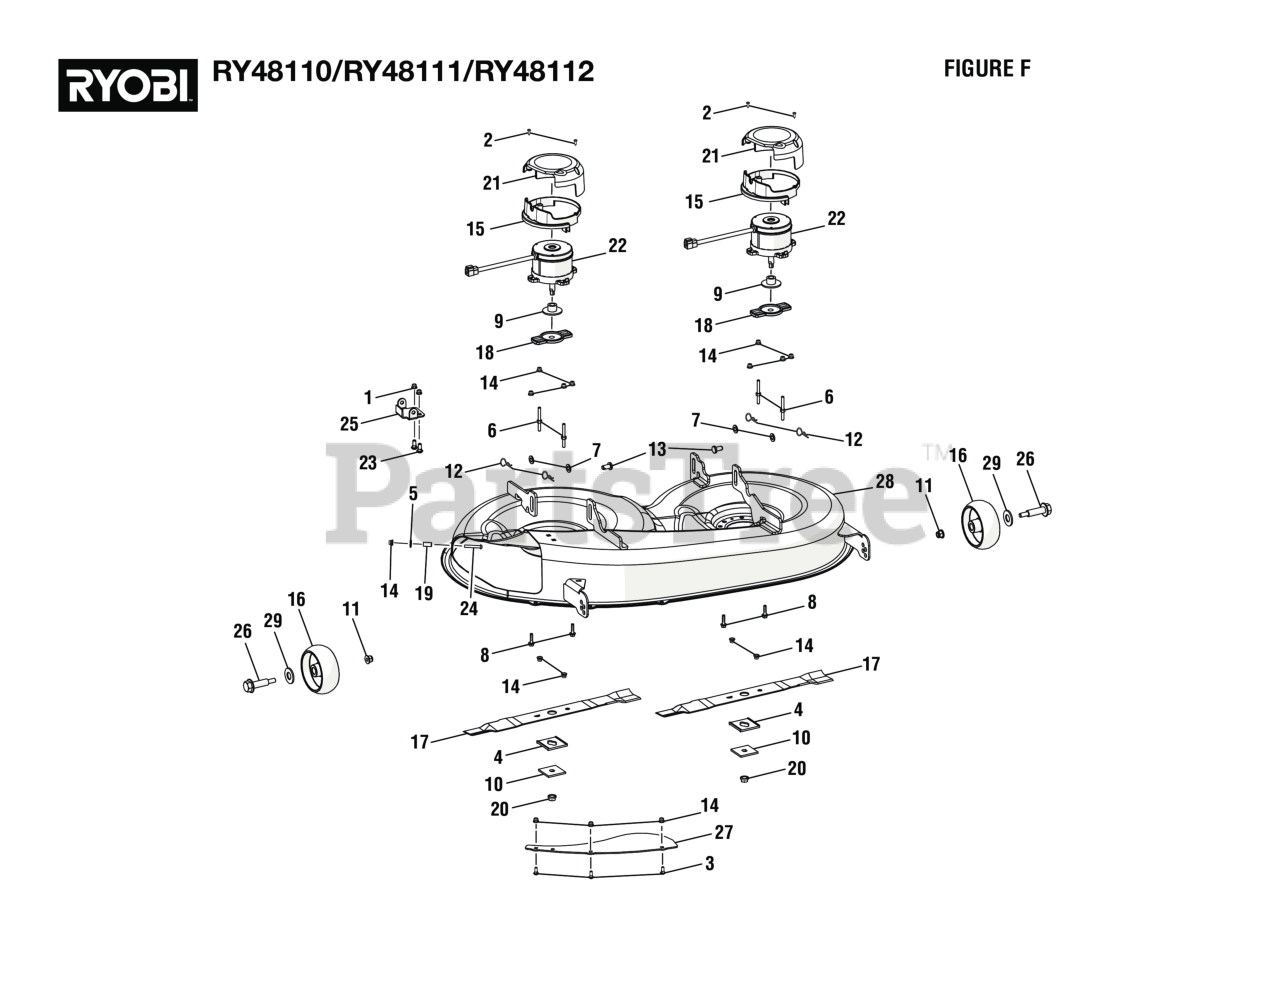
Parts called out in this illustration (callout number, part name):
1	Flange Nut (M8) (For Drive Motor Controller V)
2	Screw (ST4.2 x 13 mm)
3	Carriage Bolt (M6 x 16 mm)
4	Blade Spacer
5	Washer (OD18 x ID6.4 x 1.6t)
6	Threaded Stud (M6 x 35 mm)
7	Washer (OD20 x ID10.5 x 2t)
8	Flange Bolt (M6 x 25 mm, Hex Hd.)
9	Motor Axle Bushing
10	Metal Blade Retainer
11	Lock Nut (M10 x 1.5 mm)
12	Cotter Pin (10 mm)
13	Lifting Plate Pin
14	Flange Lock Nut (M6 x 1.00)
15	Motor Cover
16	Front Deck Roller Wheel (124.5 Dia.)
17	Mulching Blade
18	Blade Holder
19	Deck Bagger Chute Mounting Shaft
20	Flange Lock Nut (M10 x 1.25)
21	Motor Cover Cap
22	Deck Motor
23	Carriage Bolt (M8 x 20 mm)
24	Screw (M6 x 40, Soc Hd.)
25	Mounting Mulch Door Bracket
26	Shoulder Bolt (M10 x 70 mm)
27	Butterfly Bracket
28	Mower Deck w/Brackets
29	Spring Washer (OD20.5 x ID17 x 0.3t)
